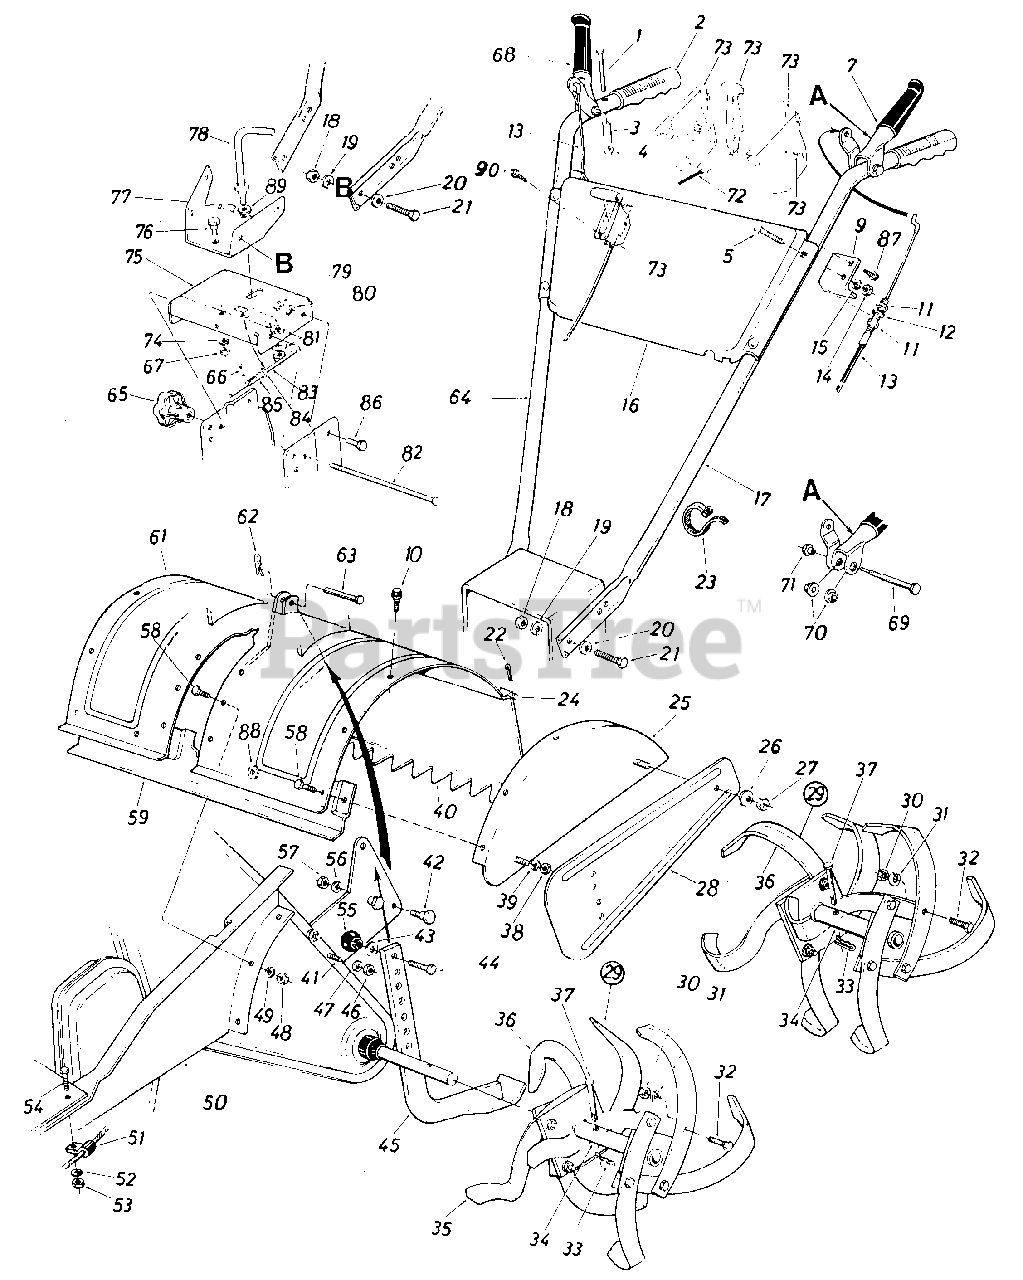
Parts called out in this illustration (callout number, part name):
1	PIN-CLEVIS-1/4 DIA X 2.25 LG
2	GRIP-BLACK
3	SPRING-COMPRESSION
5	BOLT-CARRIAGE 5/16-18 X 1.75
7	GRIP ASSY-CLUTCH-LH
9	BRACKET-CLUTCH
10	SCREW-TAP 5/16-18X.62
11	NUT-HEX JAM 5/16-24
12	WASHER-LOCK-5/16
13	CONTROL-CLUTCH
14	NUT-HEX 5/16-18
15	WASHER-LOCK-5/16
16	PANEL-HANDLE
17	HANDLE-LH
18	NUT-HEX 3/8-16
19	WASHER-LOCK-3/8
20	WASHER-BELL .400 ID X .88 X .060
21	SCREW-HEX 3/8-16 X 1.00
22	PIN-COTTER-3/32 DIA X .75
23	TIE-CABLE
24	ROD-TILLER FLAP
27	NUT-HEX 5/16-18
31	WASHER-LOCK-3/8
32	SCREW 3/8-24 X 1.25 GR5
33	PIN-COTTER
38	NUT-HEX 5/16-18
39	WASHER-LOCK-5/16
41	BOLT-HEX 5/16-18X1
42	SCREW-SHLD
43	WASHER-FL-.385 ID X .62 OD X .033
44	SCREW-HEX 3/8-16 X .75
46	NUT-HEX 5/16-18
47	WASHER-LOCK-5/16
48	NUT-HEX 5/16-18
49	WASHER-LOCK-5/16
52	WASHER-LOCK-5/16
53	NUT-HEX 5/16-18
54	SCREW-HEX 5/16-18 X .75
55	KNOB-BALL 1-3/8 " DIA.
56	WASHER-LOCK-3/8
57	NUT-HEX 3/8-16
58	SCREW-HEX 5/16-18 X .75
62	PIN-COTTER
63	PIN-CLEVIS 3/8 X 1.620
64	HANDLE-RH
66	PIN-COTTER-1/16 DIA X .75
67	NUT-HEX CENTER L-3/8-16
68	GRIP ASSY-CLUTCH-RH
69	SCREW-SHLD .374 DIA X1.530
70	BEARING-FLANGE
71	NUT-SHLD
72	WIRE-CONTROL
73	CONTROL-THROTTLE
74	WASHER-BELL .3/8ID X 1.12OD X .030
79	NUT-HEX CENTER L-3/8-16
80	WASHER-BELL .400 ID X .88 X .060
81	WASHER-BELL .505 ID X 1.00 OD
82	PIN-LOCKING
83	SLIDING ASSY-LOWER
84	WASHER-FL
85	SPRING-COMPRESSION
86	SCREW-SHLD .500 DIA X .170
87	SCREW-HEX WASH SF TAPP
88	WASHER-BELL .337 X .867 X .057
89	WASHER-.63IDX1.595ODX.62
90	SCREW-TRUSS TAP
